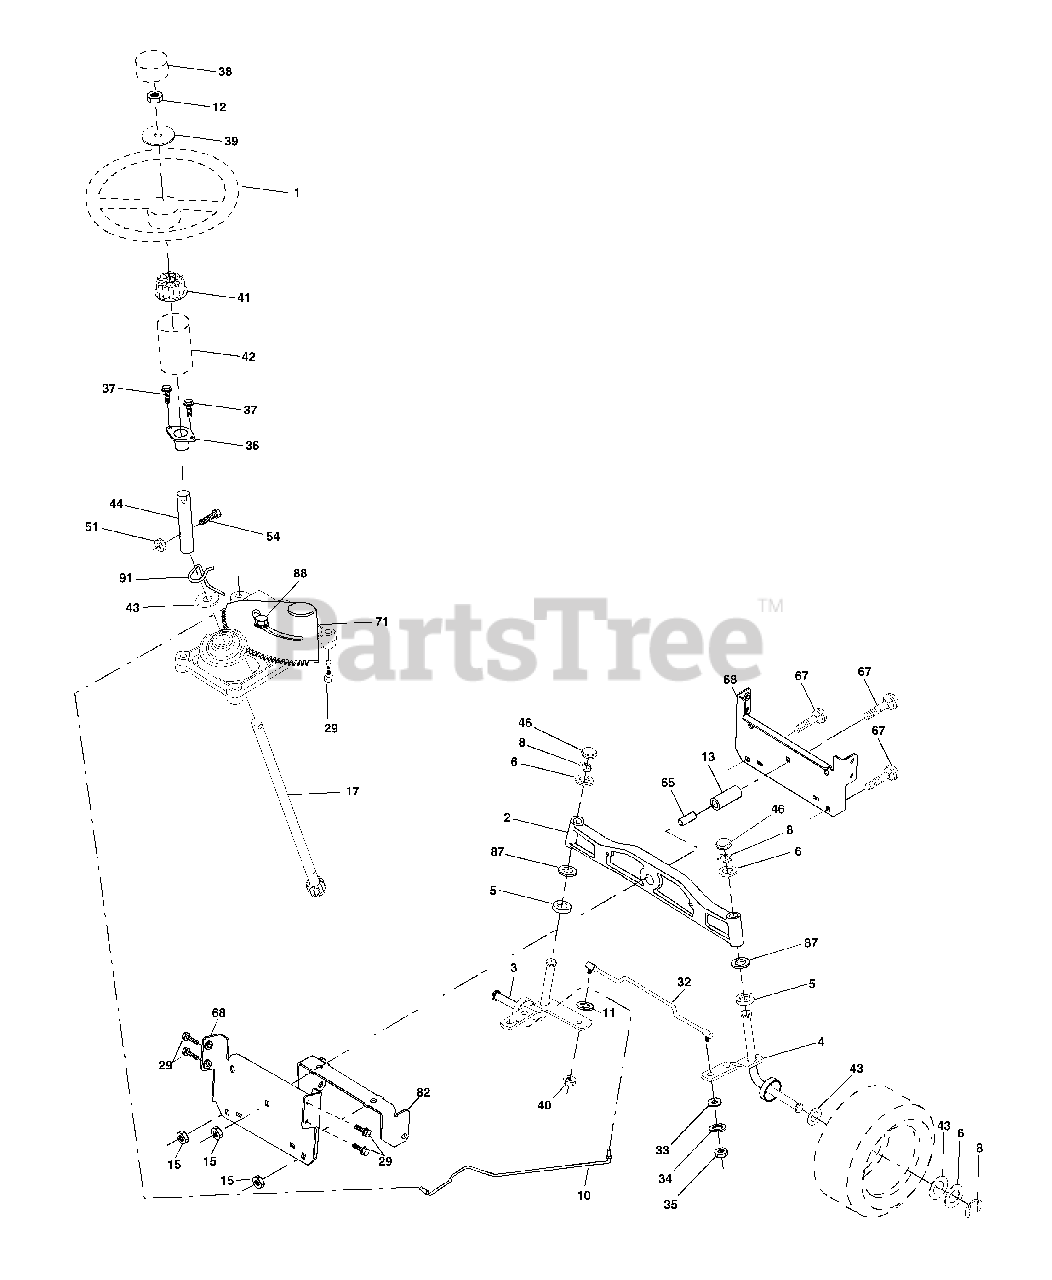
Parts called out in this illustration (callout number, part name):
1	Wheel Steering
2	Axle Asm Cast Iron LT
3	Spindle Asm LH
4	Spindle Asm RH
5	Bearing Race Thrust Harden
6	Washer 25/32 X 1-5/8 X 16 Ga
8	Ring Klip #t5304-75
10	Link Drag
11	Washer Lock Hvy Hlcl Spr 3/8
12	Nut Hex Jam Toplock 1/2-20 UNF
13	Spacer Brg. Axle Front
15	Nut Hex Flange Lock
17	Shaft Asm. Steering
29	Screw 3/8-16x.75
32	Rod Tie
33	Washer 11/32 x 3/4 x 16 Ga.
34	Washer Lock Hvy Hlcl Spr 5/16
35	Crownlock Nut 5/16-24
36	Bushing Strg
37	Screw
38	Insert Cap Strg Wh Au
39	Washer 9/16 ID x 1 1/2 OD 11 Gr.
40	Lock nut
41	Adaptor Wheel Strg
42	Boot Steering Dash/
43	Washer 25/32 X 1 1/ OD 11 Gr.4 X 16 Ga
44	Extension Steering Shaft
46	Cap Spindle Fr Top Blk
51	Nut Crownlock 1/4-28
54	Bolt Hex 1/4-28 UNF x 1-1/4 Gr. 8
65	Brace Axle
67	Bolt Rdhd Sq 3/8-16 Unc x 2-1/4
68	Axle, Brace
71	Steering Asm.
82	Bracket Susp. Chassis Front
87	Washer Flat .781 x 1-1/2 x .14
88	Bolt Shoulder 7/16-20 Unc
91	Clip Steering
